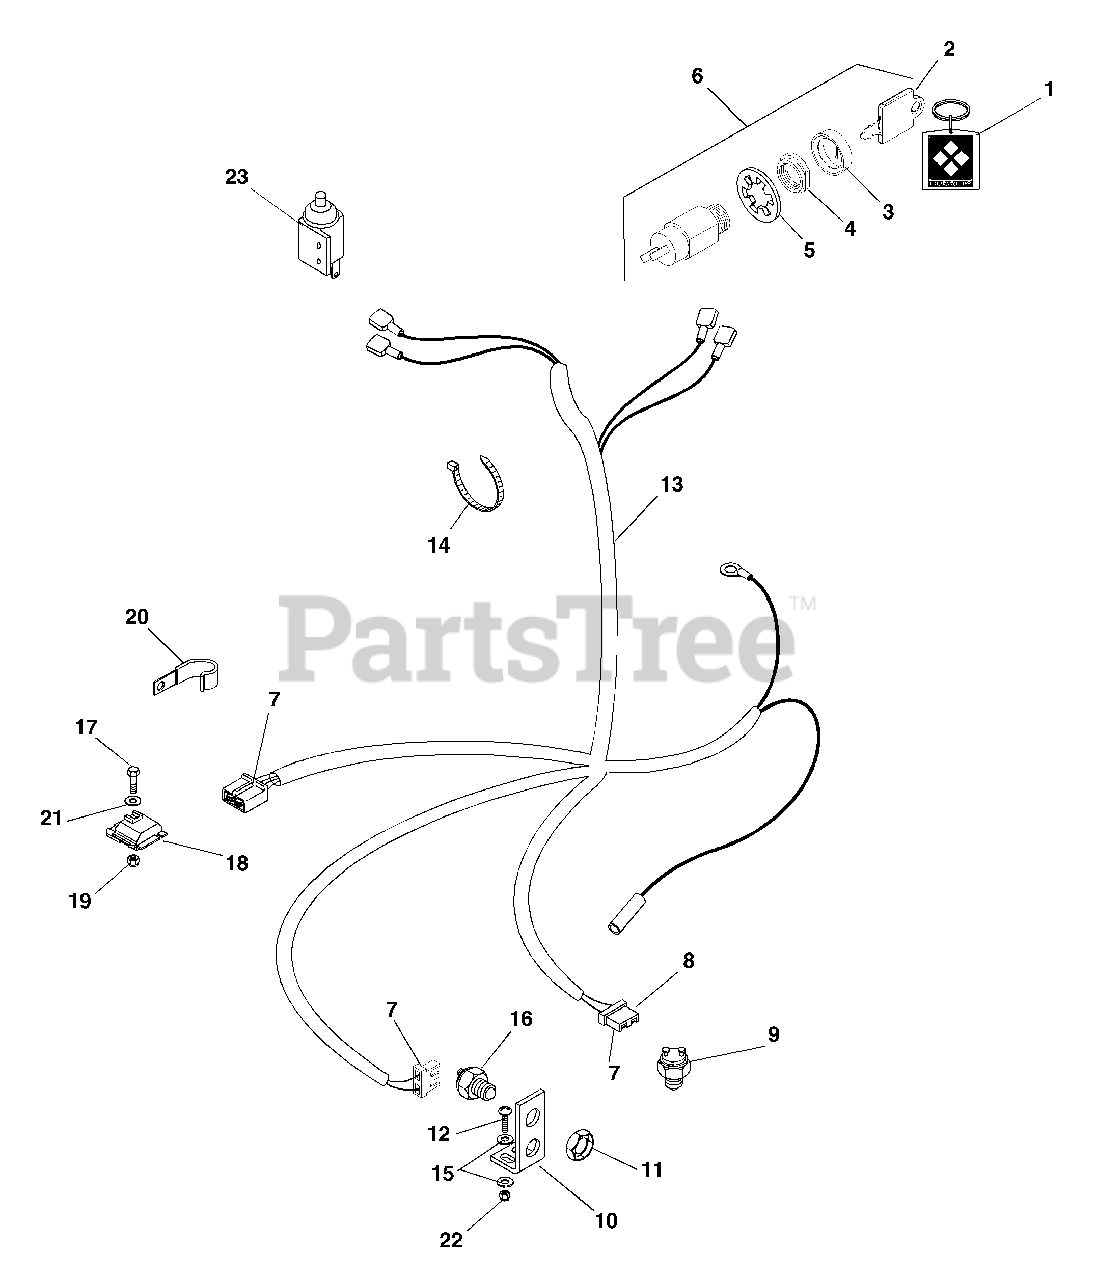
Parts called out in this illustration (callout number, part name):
1	Key Chain
2	Ignition Switch Key
3	Cap, Ignition Switch
4	Nut, Panel .625-32
5	Washer-Lock .625 Internal Tooth
6	Key Switch Assembly
7	Terminal
8	Connector, 2-Wire Switch
9	Switch, Neutral Start (N.C.)
10	Bracket, Interlock Switch
11	Nut, Stamped .56-18
12	Screw-Machine 10-24 x .75 Hex Washer Head
13	Wire Harness, Pro Recoil
14	Tie Wrap, Black
15	Washer-Flat-Steel .219 x .50 x .049
16	Switch-Neutral Start (N.O.)
17	Bolt-Hex .25-20 x .75 Grade 5
18	Module, Interlock, Electric
19	Nut-Locking-Center .25-20
21	Washer-Flat-Steel .344 x .688 x .065
22	Nut-Locking-Nylon 10-24 with Insert
23	Switch-Single Pole (N.O.) with Cover
